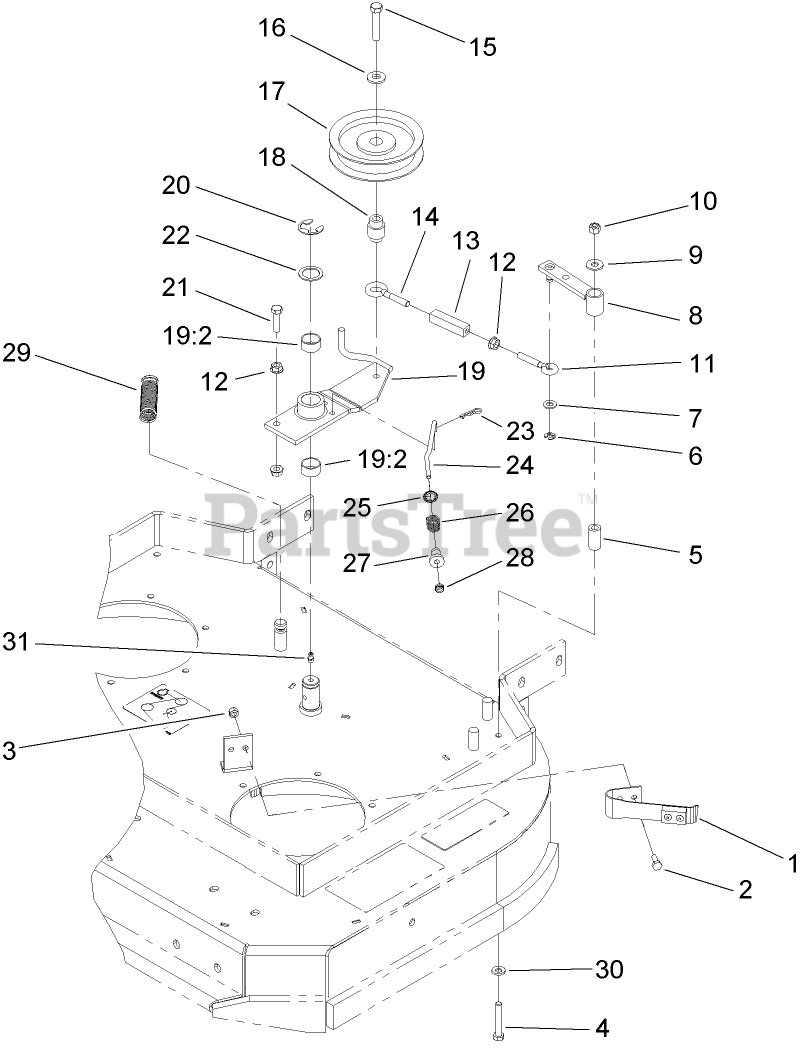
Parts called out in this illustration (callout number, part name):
1	PAD AND SPRING ASM
2	SCREW-HH
3	NUT-LOCK, NI
4	SCREW-HH
5	TUBE-PIVOT
6	RING-RETAINING, EXT
7	WASHER-PLAIN
8	ARM-ASSIST
9	WASHER-FLAT
10	NUT-LOCK, NI
11	EYEBOLT-THREAD, RH
12	NUT-HF
13	BODY-TURNBUCKLE
14	EYEBOLT-THREAD, LH
15	SCREW-HH
16	WASHER-BELLEVILLE
17	PULLEY-IDLER
18	BUSHING-ENGAGEMENT
19	Idler Arm ASM
19:2	SLEEVE-BEARING
20	RING-RETAINING, EXT
21	SCREW-HH
22	WASHER-SPINDLE
23	PIN-COTTER
24	ROD-BRAKE
25	RING-PUSH ON
26	SPRING-COMPRESSION
27	SPACER-FLANGED
28	NUT-LOCK, NI
29	SPRING-EXTENSION
30	WASHER-SPRING
31	FITTING-GREASE
